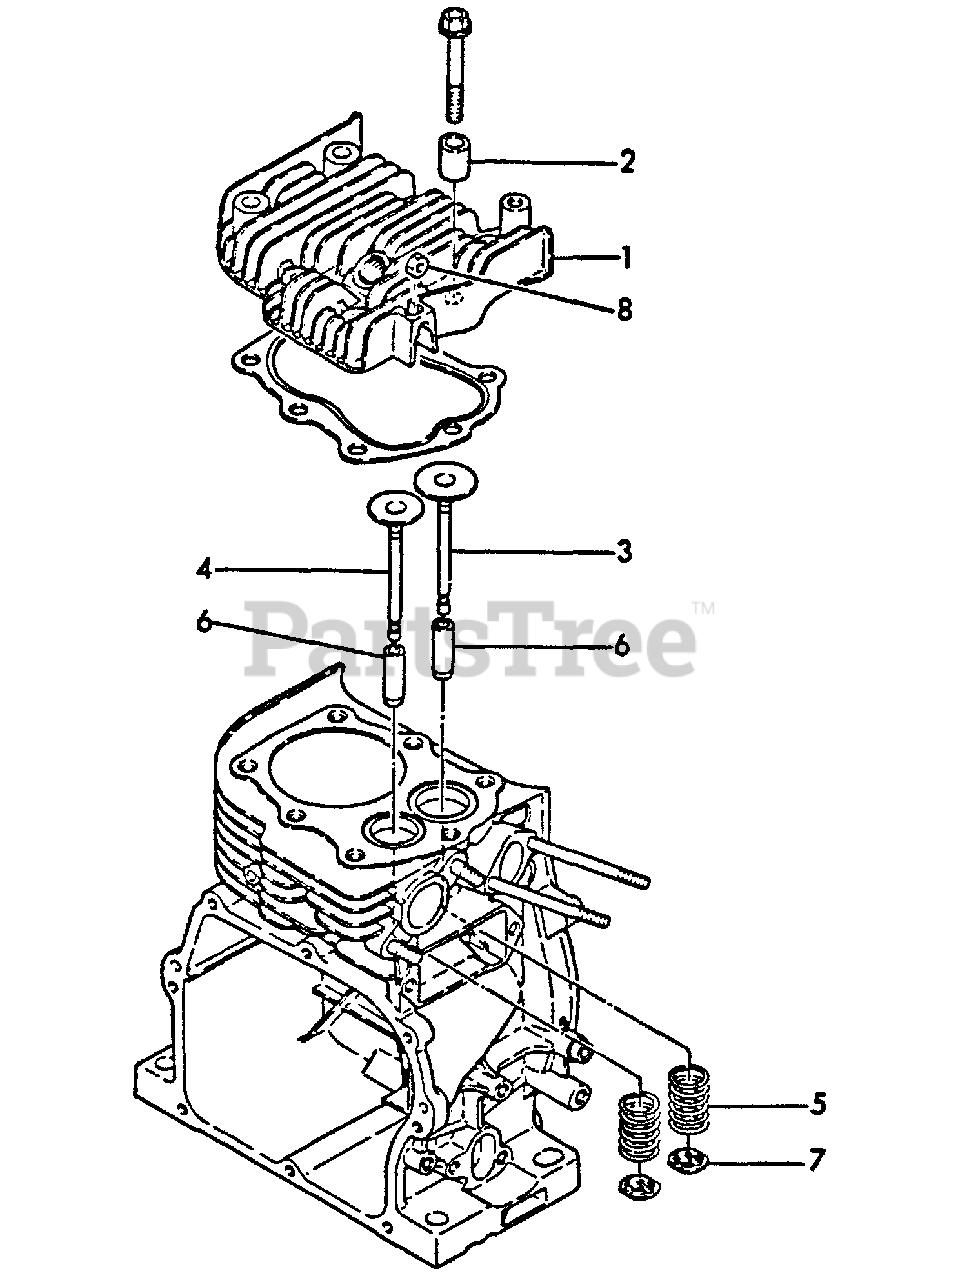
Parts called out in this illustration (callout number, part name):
1	HEAD, CYLINDER
2	SPACER
3	VALVE, INTAKE
4	VALVE, EXHAUST
5	SPRING, VALVE
6	GUIDE, VALVE
7	RETAINER, SPRING
8	LOCKNUT - 6 -- PLATED
